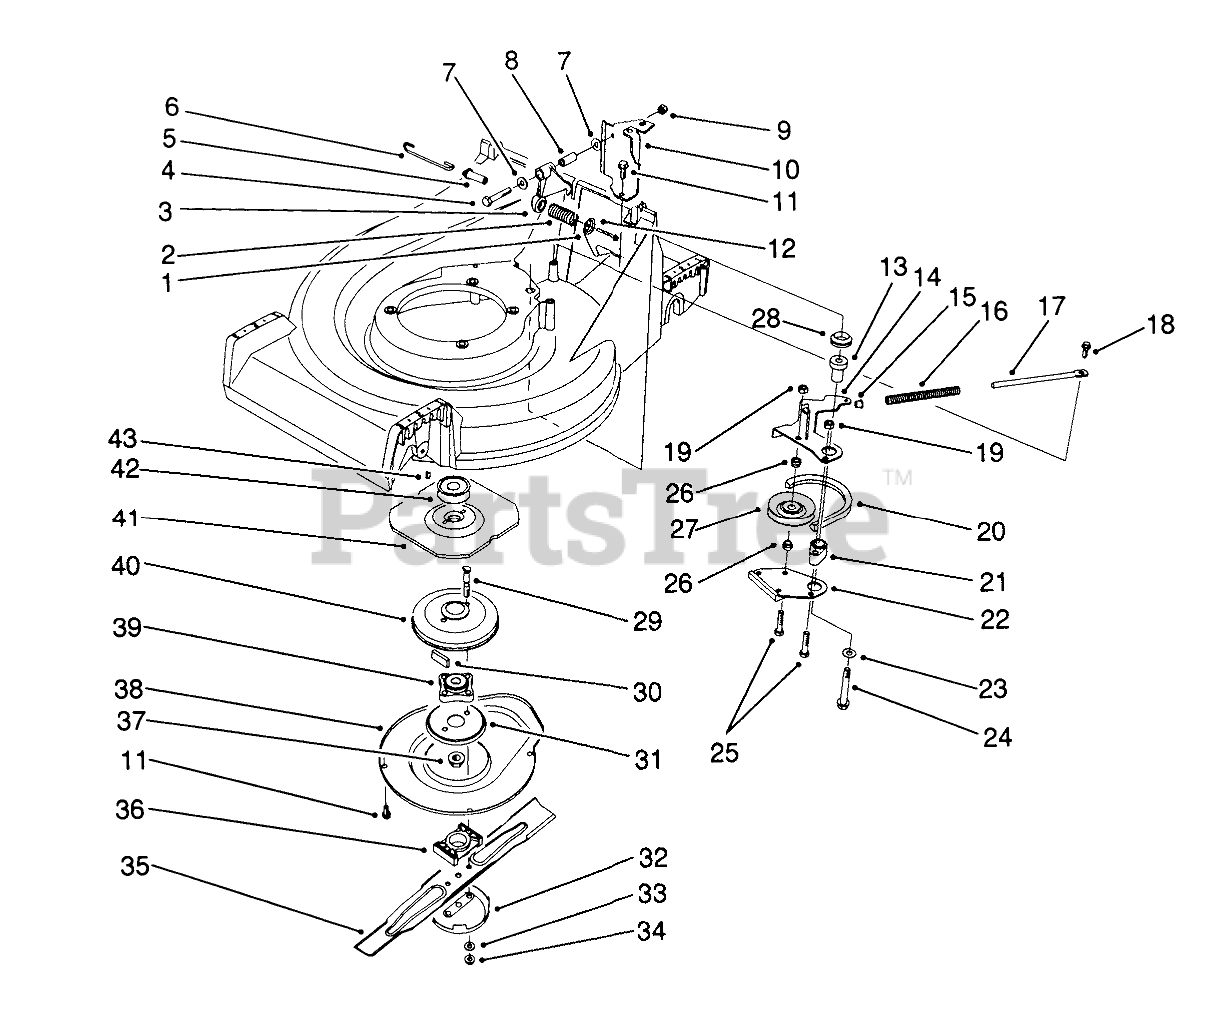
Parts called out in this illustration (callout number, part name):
1	RETAINER-SPRING
2	COMPRESSION SPRING
3	CRANK
4	SCREW-HH
5	SPRING PIN
6	CONTROL LINK
7	WASHER-PLAIN
8	STRAIGHT BUSHING
10	Bracket-Cable Support
11	SCREW-HWHTF
12	SCREW-HWHTF
13	BBC PM BUSHING
14	Lever
15	SPACER
16	COMPRESSION SPRING
17	SPRING ROD
18	SCREW-SHOULDER
19	NUT-LOCK, NI
20	V-BELT
21	BRAKE PLATE HUB
22	BRAKE SHOE
23	WASHER-PLAIN
24	3/8-16 X 2-3/4 CAPSCR
25	SCREW-HH
26	IDLER PULLEY HUB
27	PULLEY-IDLER
28	V-RING SEAL
29	BOLT-BLADE
30	DAMPENER-VIBRATION
31	Screen-BBC
32	Anti Scalp Cup
33	WASHER
34	NUT-LOCK
35	Key
36	SPACER-BLADE
37	NUT-LOCK, NI
38	Cover
39	HUB ASM
40	BRAKE DRUM
41	FLYWHEEL - BBC
42	PULLEY
43	KEY-WOODRUFF
